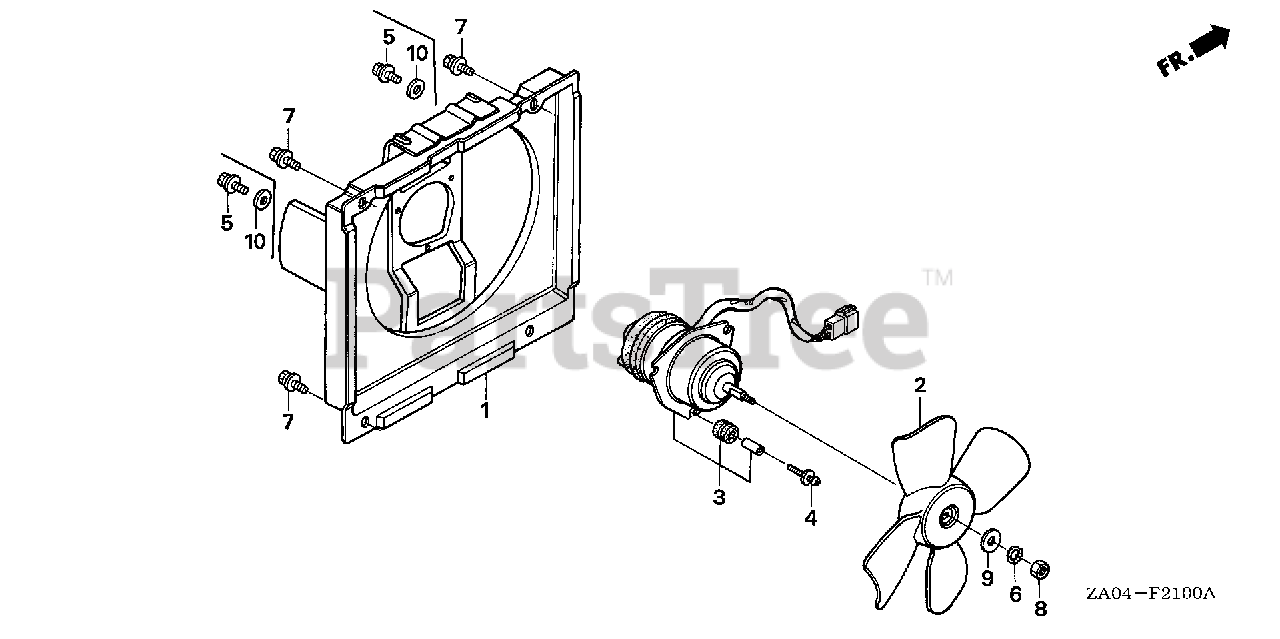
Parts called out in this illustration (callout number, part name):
2	FAN, COOLING (TOYO)
3	MOTOR, COOLING FAN (MITSUBA)
4	SCREW-WASHER (4X20) (TOYO)
5	BOLT-WASHER (6X10) (TOYO)
6	WASHER (TOYO)
8	NUT, HEX. (5MM)
9	WASHER, PLAIN (5MM)
10	WASHER, PLAIN (6MM)
